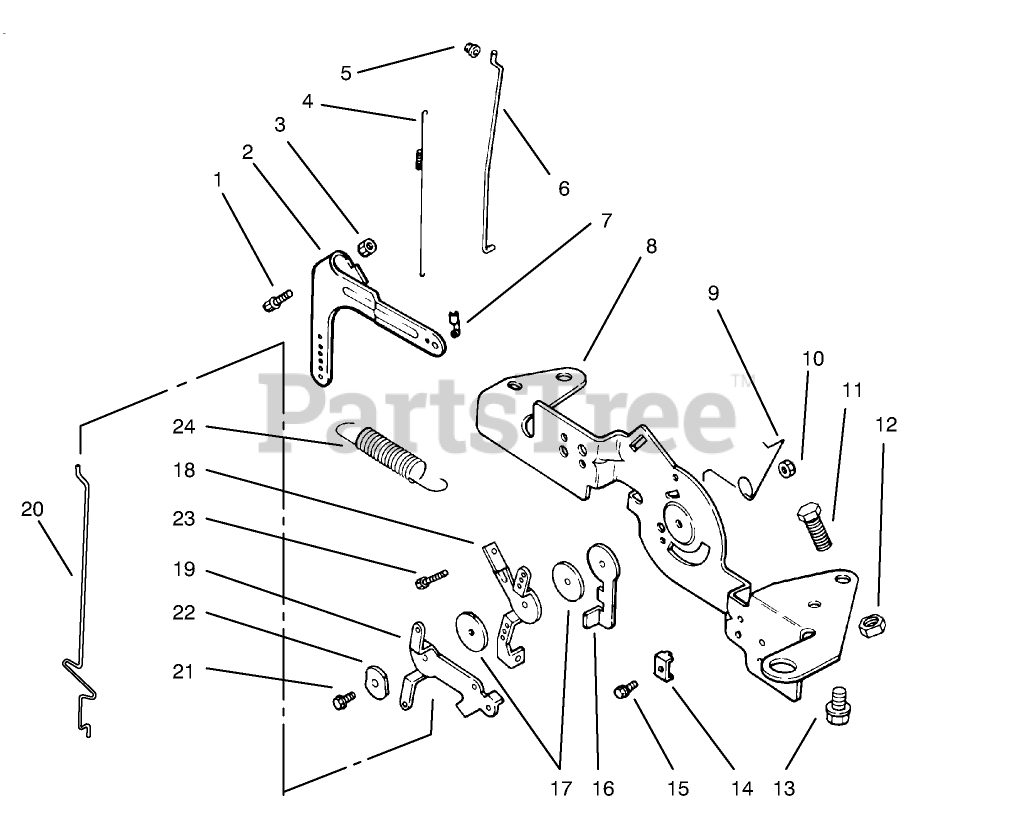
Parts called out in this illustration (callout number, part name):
2	Lever-Governor
4	Spring-Linkage
5	Bushing
6	Linkage-Throttle (Only On: 72103)
7	Bushing-Linkage
8	Bracket-Control
9	Spring-Choke Return
16	Lever-Throttle Actuator
18	Lever-Throttle Control
19	Lever-Choke
20	Linkage-Choke (Only On: 72103, 72083)
22	Washer-Wave
23	Screw-Hex.
24	Carriage Bolt
